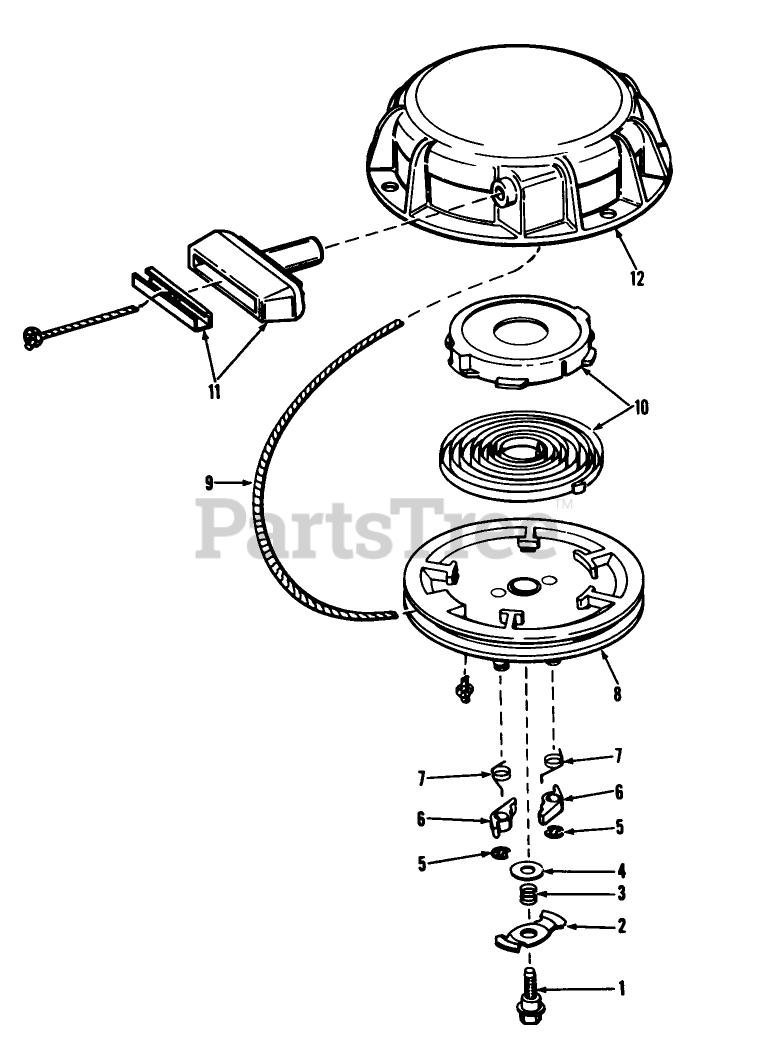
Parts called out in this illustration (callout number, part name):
1	Screw, Center
2	Cam, Dog
3	Spring, Brake
4	Washer, Brake
5	Ring, Retainer
7	Spring, Dog
8	Pulley
9	Rope-Starter
10	Spring & Keeper Assy.
11	Assy., Starter
12	Housing Assy., Starter
